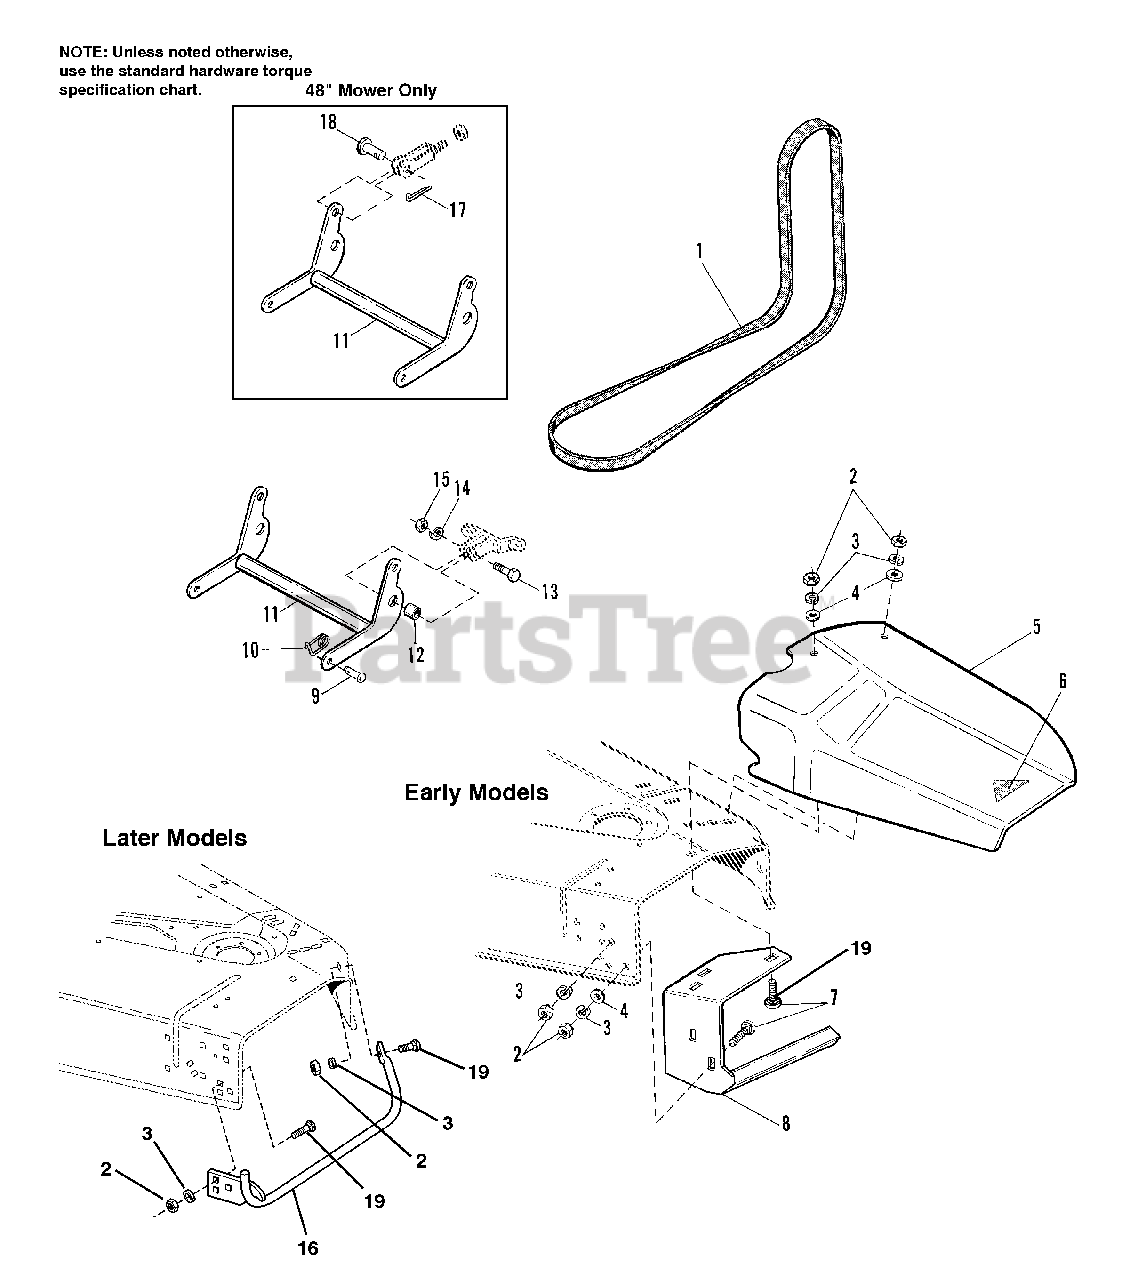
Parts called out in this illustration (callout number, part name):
1	BELT, "V", PTO to Mower
2	NUT, Hex, Full, 3/8-16
3	LOCKWASHER, 3/8
4	WASHER
5	DEFLECTOR - (Orange)
5	DEFLECTOR - (Black)
6	DECAL, OPEI
7	CARRIAGE BOLT, 3/8-16 x 1-1/4
8	GUARD ASSEMBLY, Stone
10	PIN, Clip
11	ROCKER ARM ASSEMBLY
13	CAPSCREW, Hex Hd, 1/2-13 x 1-1/4
14	LOCKWASHER, 1/2
15	NUT, Hex, Jam, 1/2-13
16	STONE GUARD ASSEMBLY
17	PIN, Cotter, 1/8 x 1
18	PIN, Yoke
19	CARRIAGE BOLT, 3/8-16 x 1
